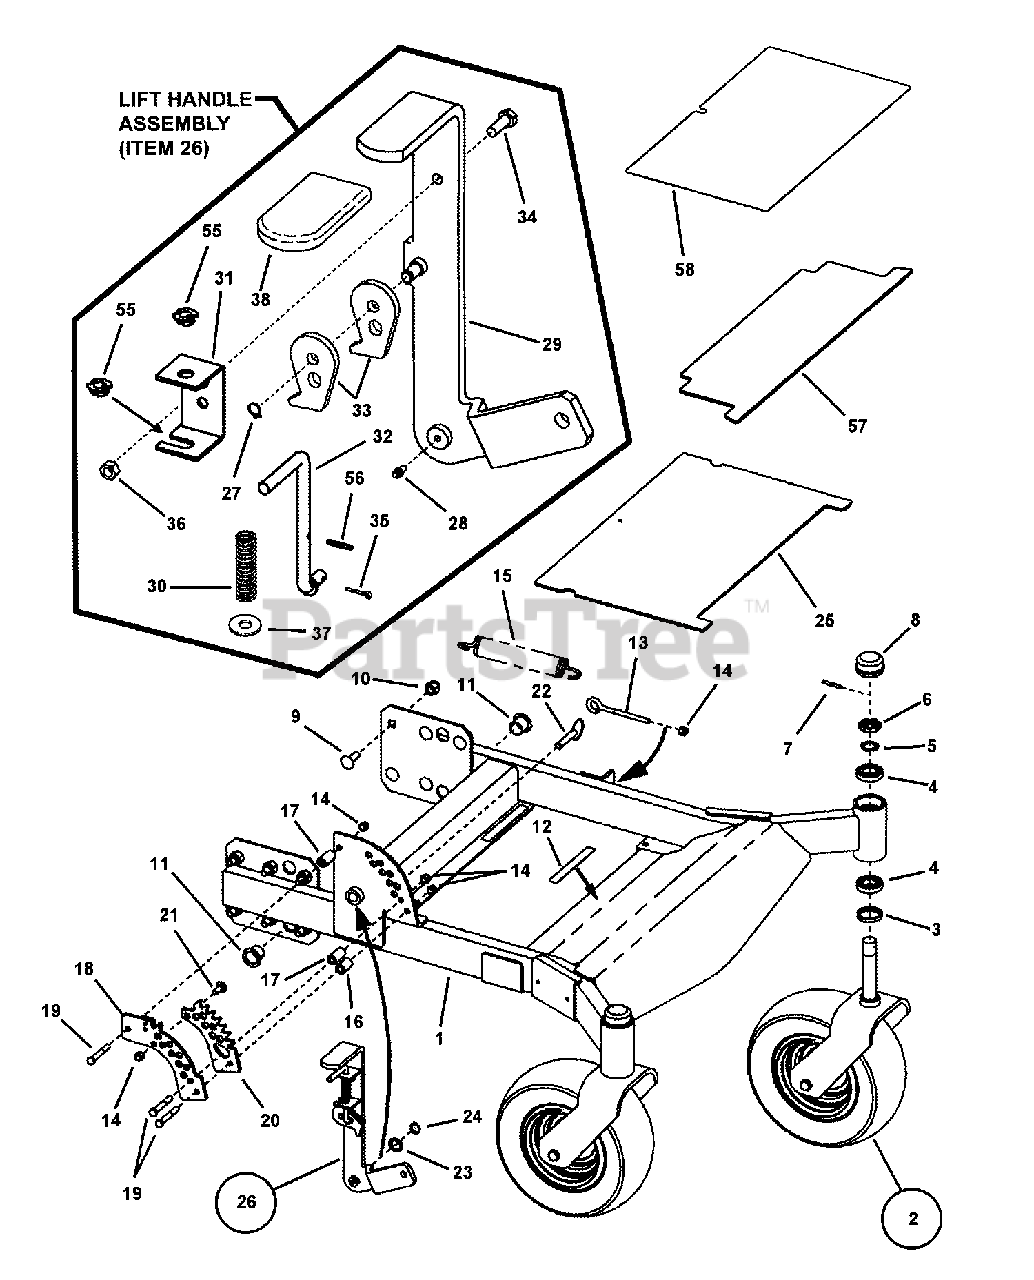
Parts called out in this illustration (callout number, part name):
1	WELDMENT, Front Frame
2	GROUP, Front Wheel (see Caster Wheel Assembly Page)
3	GREASE SEAL
4	BEARING, Tapered Roller
5	SPACER, Jackstaff
6	CASTLE NUT, 1-1/ UNF, GR B
7	ROLL PIN, 3/16 x 1-1/2"
8	CAP, 3-1/2" Fuel
9	BOLT, 1/2-13 x 1-1/2" Square Neck Carriage GR5
10	NUT, 1/2-13 Hex Nyloc
11	BUSHING, Teflon
12	PAD, Floor Pan
13	EYEBOLT, 3/8-16 x 3"
14	NUT, 3/8-16 HEX NYLON LOCK
15	SPRING, Extension, Lift Assist
16	SPACER, Lift Adjust (1.08" Long)
17	SPACER, Lift Adjust (1.43" Long)
18	WELDMENT, Height Adjust
19	BOLT, 3/8-16 X 2-1/2" GD5 CZ
20	BRACKET, Deck Lift Detent
21	BOLT, 3/8-16 x 1" Square Neck Carriage GR5
22	CLIP, Roll Pin, 1/2"
23	WASHER, .77 I.D. Flat
24	RING, 3/4" External Retaining
25	FLOORPAN
26	ASSY, Deck Lift Handle (Incl. indented items below)
27	RING, .375" Diameter External Retaining
28	LUBE FITTING, 3/16" (or 76998, 1/4-28 Straight Lube Fitting)
29	WELDMENT, Deck Lift Handle
30	SPRING, Neutral Return
31	BRACKET, Handle Support
32	ROD, Latch
33	STOP, Latch
34	SCREW, 5/16-18 x 1" Hex Head Cap, GR2
35	PIN, 3/32 x 1/2" Cotter
36	NUT, 5/16-18 Hex Center Lock
37	WASHER, 3/8" Flat SAE
38	COVER, Plastic
55	BUSHING, 3/8 Plastic
56	ROLLPIN,1/8 x 7/8"
57	MAT, Footpan
58	MAT, Floor Pan
